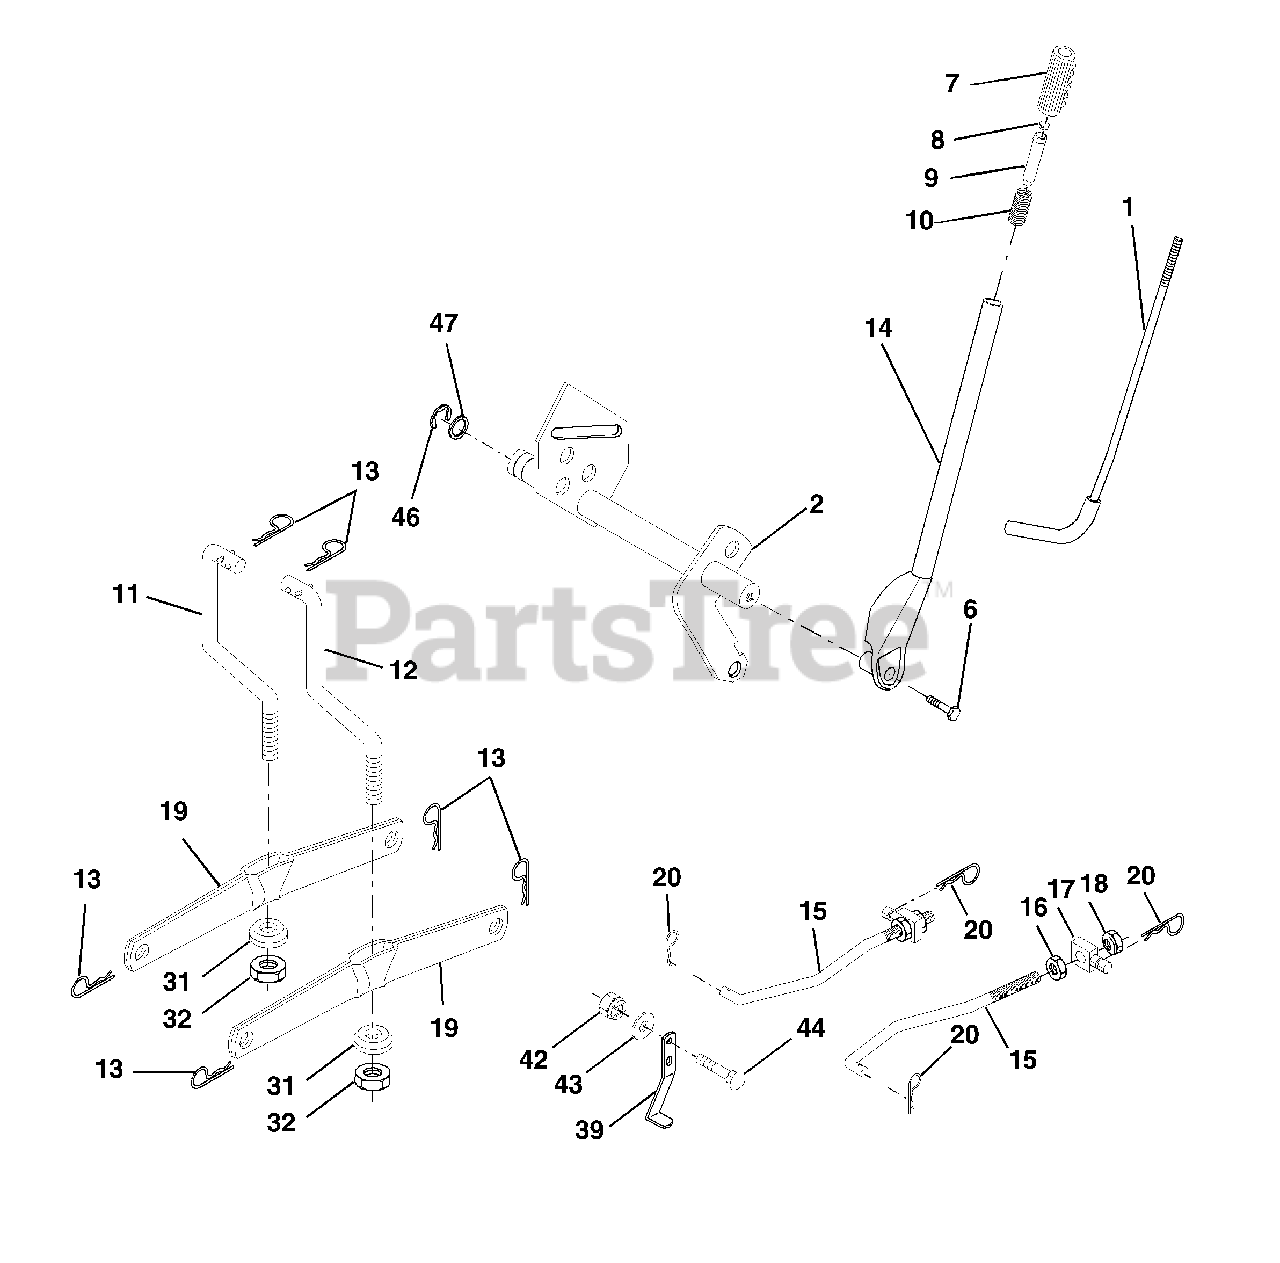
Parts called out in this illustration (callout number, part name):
1	Rod Assembly, Lever
2	Shaft Assembly, Lift
6	Bolt, Hex Head, Fin. 3/8-16 x 1-1/2
7	Grip Handle
8	Button Plunger Black
9	Plunger Lever Lift
10	Spring
11	Link, Lift, LH
12	Link, Lift, RH
13	Retainer Spring
14	Lever Assembly, Lift, RH
15	Link, Front
16	Nut, Hex, Jam 1/2-13 UNC
17	Trunnion
18	Nut Lock W/Wsh 1/2-13 Unc
19	Arm, Suspension, Rear
20	Retainer Spring
31	Bearing
32	Nut, Crownlock 3/8-24
39	Stop Over Center
42	Nut, Crownlock 3/8-16 UNC
43	Washer 13/32 x 1 x 12 Ga.
44	Bolt, Carriage 3/8-16 x 1.00
46	E-Ring
47	Washer
